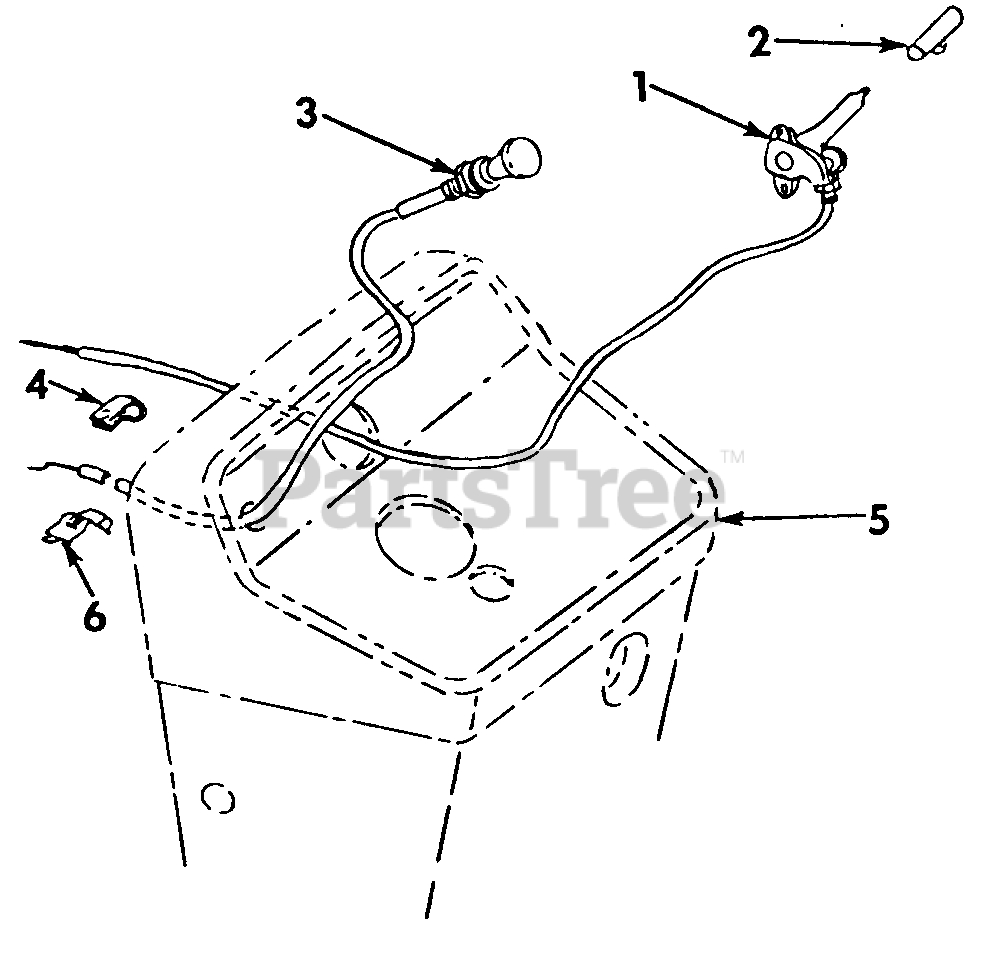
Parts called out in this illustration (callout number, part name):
1	Lever and Cable Assy, Throttle
2	Knob, Throttle Control
3	Cable Assy, Choke
4	Clip, Throttle Cable Retainer
5	Cowl, Instrument Panel
6	Clip, Choke Cable
